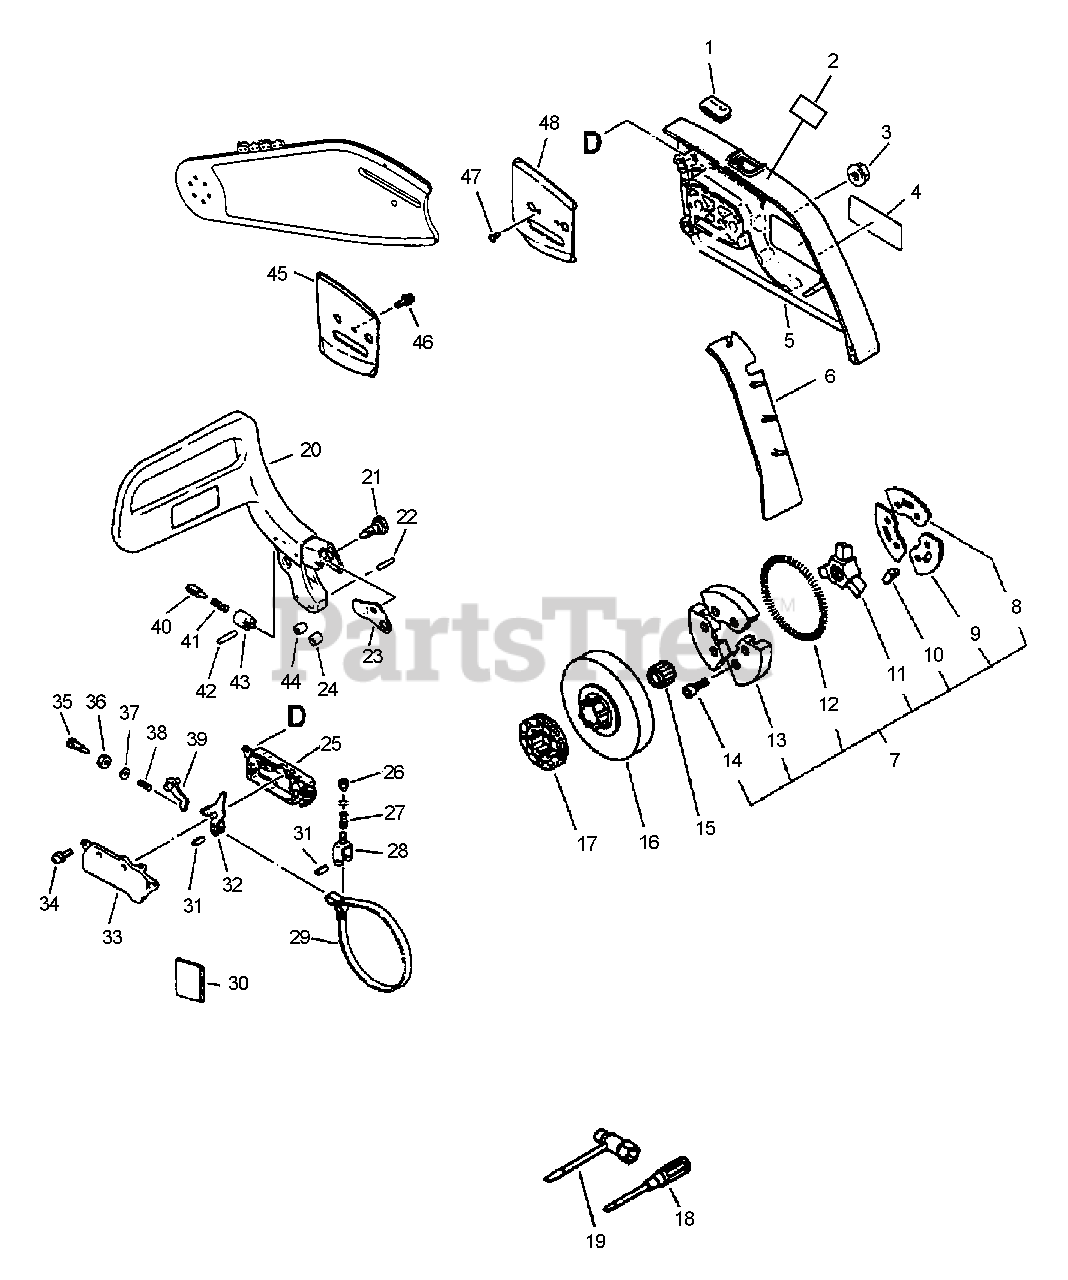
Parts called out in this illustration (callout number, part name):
2	LABEL - CAUTION
3	NUT - FLANGE
4	LABEL - ECHO
5	GUARD, SPROCKET
7	CLUTCH ASSY
8	PLATE, CLUTCH
9	PLATE, CLUTCH
10	PLATE, SPRING
11	HUB, CLUTCH
12	SPRING, CLUTCH
13	CLUTCH SHOE SET
14	SCREW - 4X8
15	BEARING, NEEDLE
16	DRUM, CLUTCH
17	SPROCKET, RIM
18	SCREWDRIVER
19	T-WRENCH - 13X19mm
20	LEVER, BRAKE
25	COVER, BRAKE
28	ADJUSTER, BRAKE BAND
29	BAND, BRAKE
31	PIN - SPRING
32	LEVER, BRAKE
33	COVER, BRAKE
34	SCREW - 4X10
38	SPRING, BRAKE
39	STOPPER, BRAKE
44	SPACER
45	PLATE, GUIDE - INNER
46	SCREW - 4X10
47	SCREW - 3X6
48	PLATE, GUIDE - OUTER
